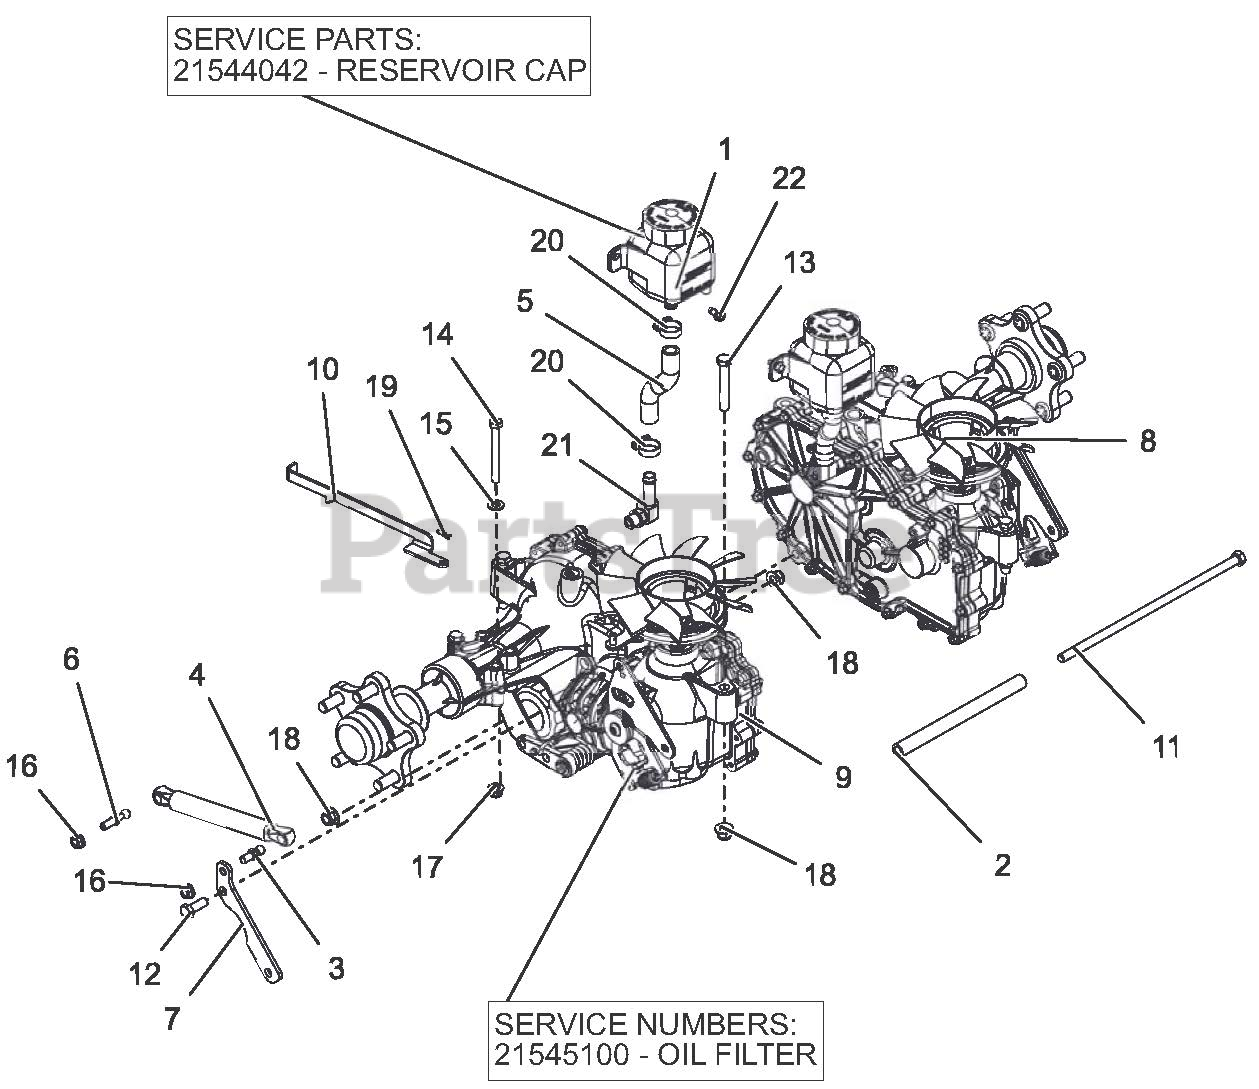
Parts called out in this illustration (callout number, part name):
1	TANK, EXPANSION ZT2800
1	RESERVOIR CAP
2	SPACER, .406 ID X .630 OD X 7.724
3	STUD-BALL
4	DAMPER
5	HOSE, PT100 HYDRO OVERFLOW
6	STUD, BALL THREADED
7	TRANSMISSION DAMPER MTG PLATE-BLK
8	TRANSAXLE, ZT3200 - LH
9	TRANSAXLE, ZT3200 - RH
9	OIL FILTER
10	BRKT, DUMP VALVE
11	BLT, HEX .38-16 X 11.00 GR5 YWZC
12	BLT-HEX .38-16 X 1.00 GR5 YWZC
13	BLT-HEX .38-16 X 2.50 GR5 YWZC
14	BLT-HEX .31-18 X 3.00 GR5 YWZC
15	WSHR-FL-STL .344 X .688 X .065 YWZC
16	NUT, LK-TOP-FLG .312-18 YWZC
17	NUT-LK-NYL-FLG .31-18 YWZC
18	NUT-LK-NYL-FLG .38-16 YWZC
19	PIN-HAIR INT .06 X .18 X .77
20	CLAMP, .88 DIA HOSE
21	FITTING, HYD
22	SCR-TAP .25-20 X .50 HWH TR YWZ
